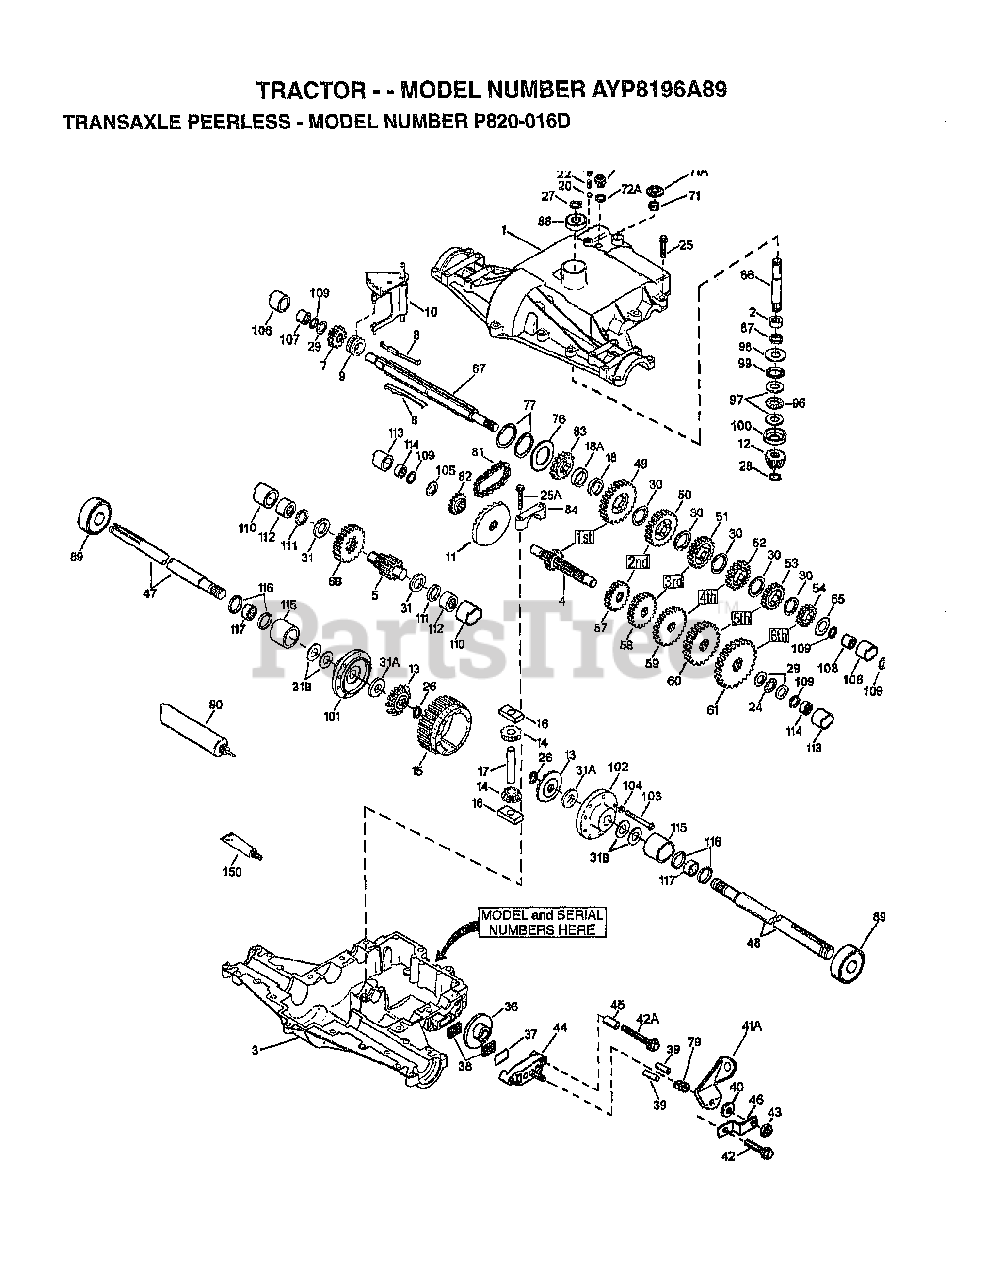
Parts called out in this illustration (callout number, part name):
1	COVER TRANSAXLE
2	BEARING NEEDLE
3	CASE TRANSAXLE
4	SHAFT COUNTER
5	SHAFT, OUTPUT, 9T
6B	GEAR, OUTPUT, 35T
7	GEAR, SPUR, 15T
9	COLLAR, SHIFTER
11	GEAR BEVEL, 33T
12	BEVEL PINION, 13T
14	PINION, 10T
15	GEAR, RING, 31T
16	BLOCK DRIVE
18	SPACER, .350/.340 THICK
18A	SPACER, .276/.268 THICK
20	BALL STEEL, 5/16" DIA.
21	SCREW, 3/8-16 X 3/8"
24	THRUST BEARING
25	SCREW, 5/16-18 X 1-1/4
28	RETAINING RING
29	WASHER THRUST
30	WASHER THRUST
31	WASHER THRUST
31B	WASHER THRUST
37	PLATE BRAKE PAD
41A	LEVER BRAKE
42A	SCREW, 1/4-20 X 2-1/4
43	LOCKNUT 5/16-24
44	HOLDER BRAKE PAD
46	BRKT BRAKE LEVER
47	AXLE, 12-5/16" LONG
48	AXLE, 16-3/16" LONG
49	GEAR, SPUR, 41T
50	GEAR, SPUR, 35T
51	GEAR, SPUR, 30T
52	GEAR, SPUR, 25T
53	GEAR, SPUR, 22T
54	GEAR, SPUR, 19T
57	GEAR, SPUR, 15T
58	GEAR, SPUR, 20T
59	GEAR, SPUR, 25T
60	GEAR, SPUR, 28T
61	GEAR, SPUR, 31T
65	WASHER, THRUST
66	SHAFT INPUT
67	SHIFTER & BRAKE SHAFT
71	SEAL SQUARE CUT
72	THREADED PLUG 9/16-18
76	WASHER, THRUST
77	INVERTED RETAINING RING
81	CHAIN, ROLLER
82	SPROCKET 9T
83	SPROCKET 18T (REV)
84	BEARING CAP
87	OIL SEAL 3/4
88	BEARING BALL
89	BEARING BALL
90	GREASE BENTONITE, 32 OZ.
96	BEARING THRUST
97	WASHER THRUST
100	WASHER CUPPED
101	CARRIER DIFF THREADED HOLES
102	CARRIER DIFF
103	SCREW, 1/4-20 X 2-1/4
104	WASHER LOCK 1/4
107	BEARING NEEDLE
108	BEARING NEEDLE
110	SLEEVE STEPPED
111	RING SQ CUT
112	BEARING NEEDLE CAPPED
113	SLEEVE STEPPED
114	BEARING NEEDLE CAPPED
115	SLEEVE STEPPED
116	RING SQ CUT
117	BEARING NEEDLE
150	LIQUID GASKET RTV SILICONE
